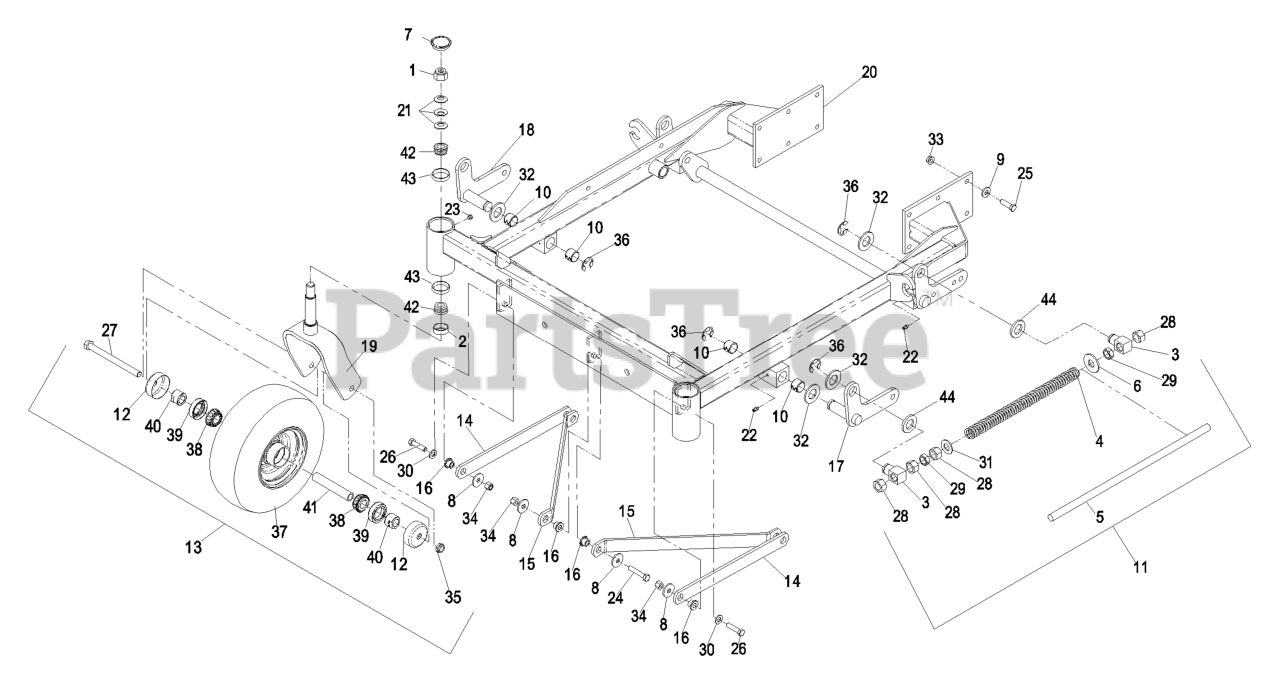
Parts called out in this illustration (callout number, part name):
1	NUT-LOCK, NI
2	SEAL-GREASE
3	SWIVEL-DECK MOUNT, REAR
4	SPRING-COMPRESSION
5	ROD-LIFT, DECK
7	CAP-GREASE
9	WASHER-BELLEVILLE
10	BUSHING,SPRING
11	FRONT SPRING ASM
12	GUARD-SEAL
13	WHEEL AND TIRE ASM
14	FLAT,STRUT
15	FLAT,STRUT ANGLED
16	SPACER-STRUT
17	WLD,SHAFT LH
18	WLD,SHAFT RH
19	FORK-CASTER
20	ASM, FRONT FRAME
21	WASHER-BELLVILLE
22	FITTING-GREASE
24	SCREW-HH
25	SCREW-HH
26	SCREW-HH
27	SCREW-HH
28	NUT-HEX
29	NUT-JAM
30	WASHER-FLAT
31	WASHER-FLAT
32	WASHER-FLAT
33	NUT-HHF, WHIZ
34	NUT-LOCK, NI
35	NUT-HEX
36	RING-RETAINING, EXT
38	BEARING-CONE, TAPERED ROLLER
39	SEAL-CASTER
40	SPACER-NUT
42	Cone-Bearing Tapered Roller
43	CUP-BEARING
44	WASHER-FLAT
